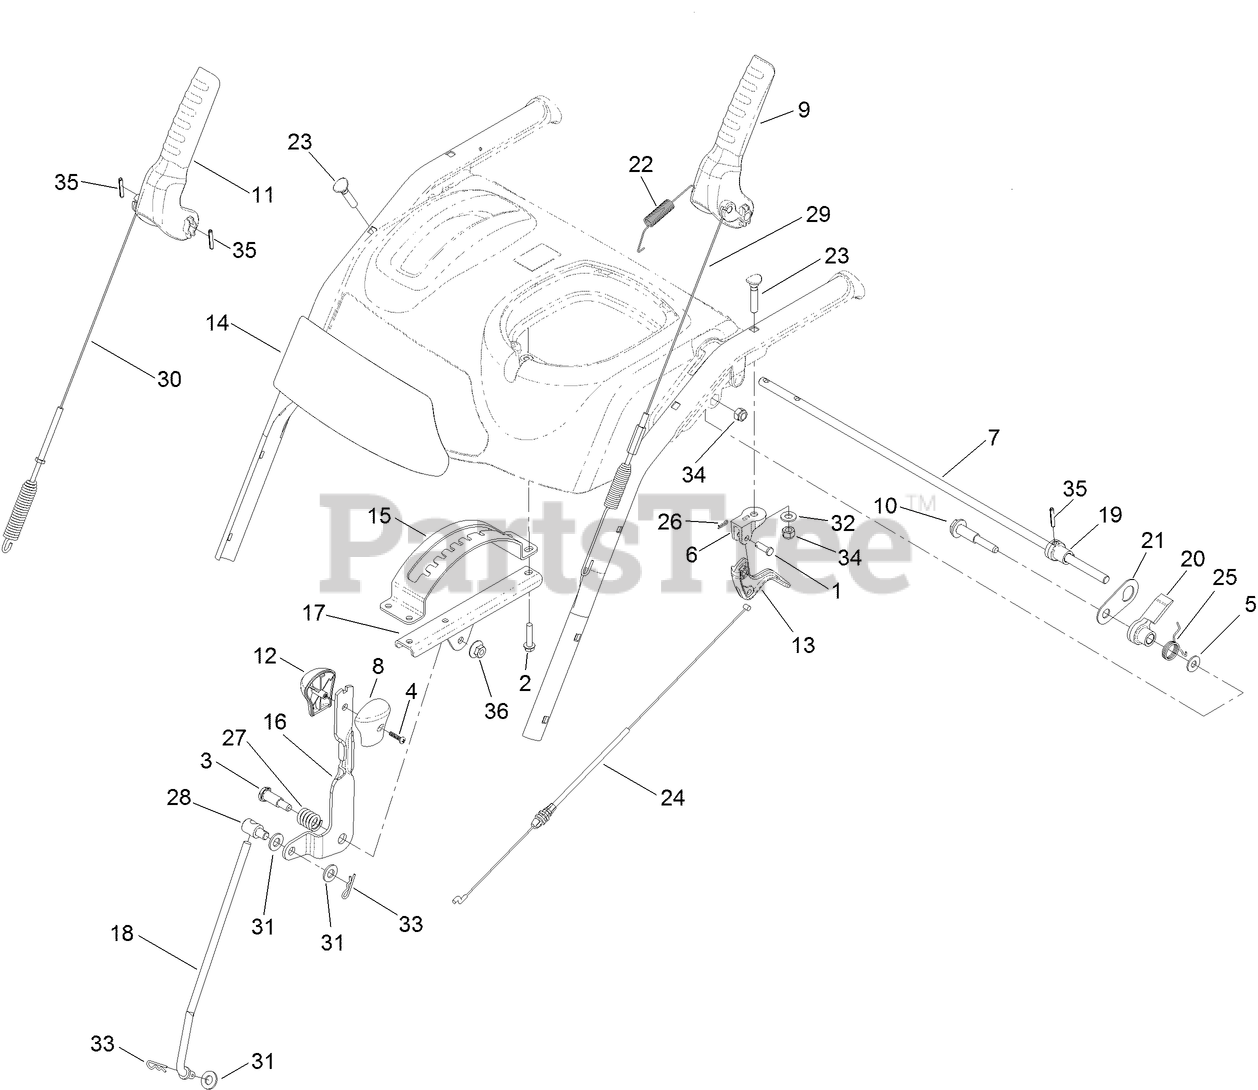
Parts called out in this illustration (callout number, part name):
1	PIN-CLEVIS
2	SCREW-PLASTITE
3	SCREW-SHOULDER
4	SCREW-PPH
5	WASHER-FLAT
6	MOUNT-LEVER, CLUTCH
7	ROD-LOCKOUT
8	KNOB-SHIFT, LH
9	LEVER-TRACTION
11	LEVER-AUGER
12	KNOB-SHIFT, RH
13	LEVER-CLUTCH
14	DECAL-CONTROL PANEL
15	GUIDE-SELECTOR, SPEED
16	SELECTOR-SPEED
17	BRACKET-SELECTOR, SPEED
19	CAM-LOCKOUT
20	LATCH-LOCKOUT
21	LINK-LOCKOUT
22	SPRING-TENSION
23	SCREW-HANDLE
24	CABLE-CLUTCH
25	SPRING-TORSION
26	PIN-HAIR
28	TRUNNION-ROD
29	CABLE-TRACTION
30	CABLE-AUGER
31	WASHER-FLAT
32	WASHER-FLAT
34	NUT-LOCK, NI
35	PIN-SPRING
36	NUT-HF
